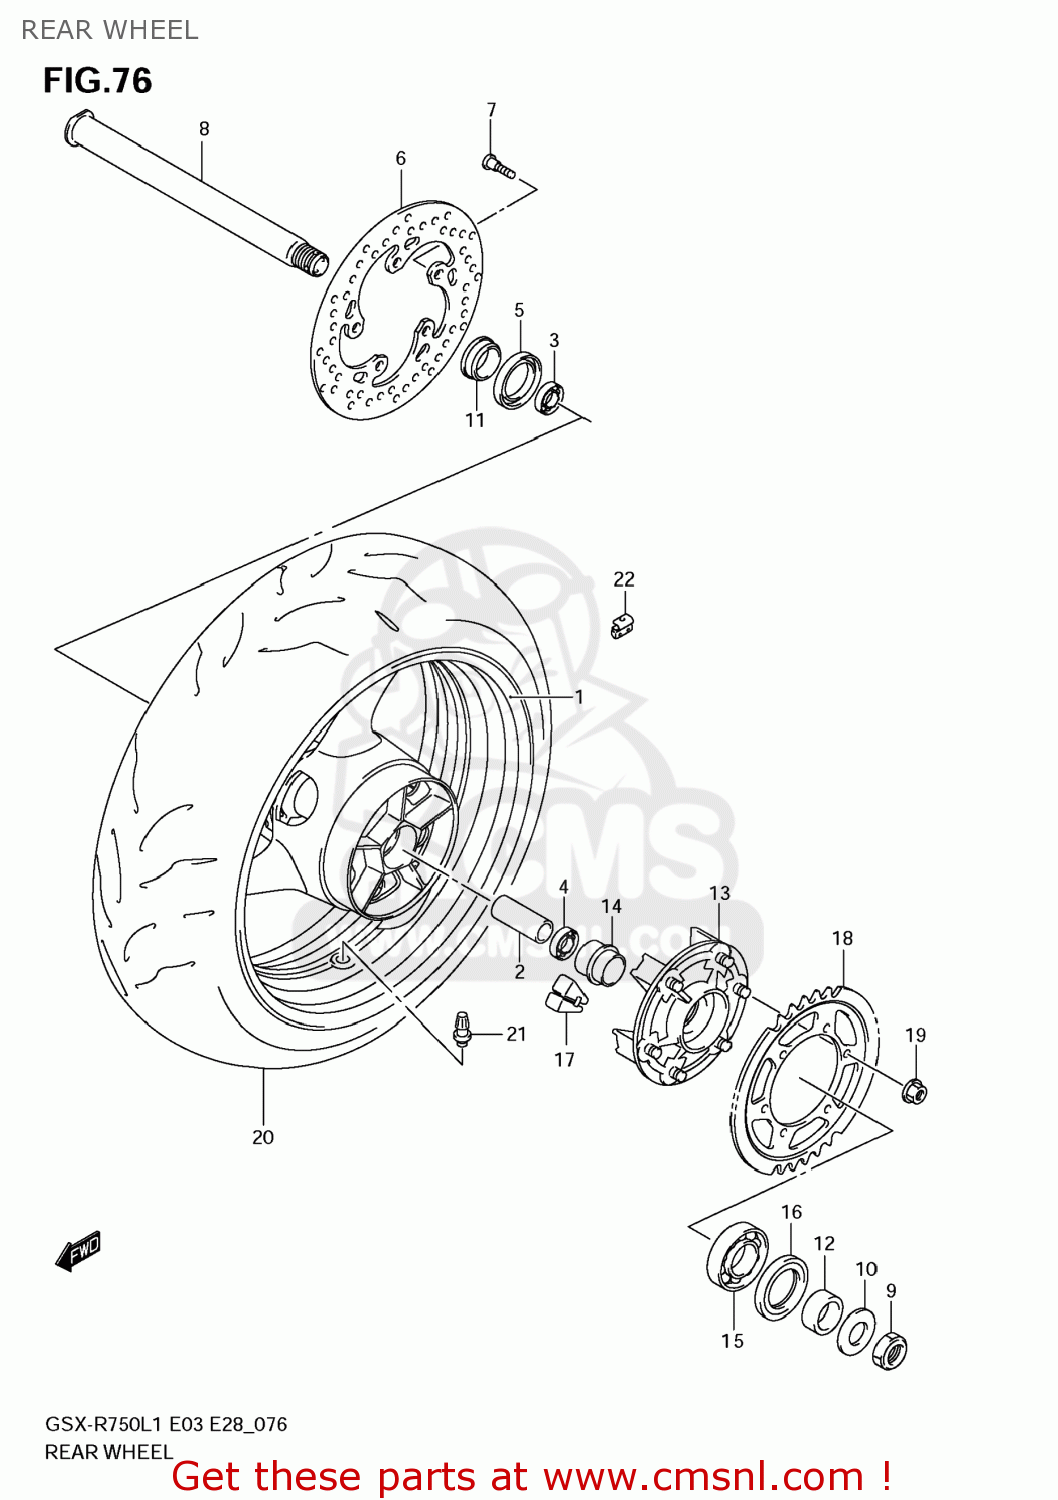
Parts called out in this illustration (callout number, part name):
1	WHEEL,RR(17M/CXMT5.50)
2	SPACER,RR WHEEL BEARING
3	BEARING(25X52X15)
4	BEARING
5	SEAL,OIL(32X52X7)
6	DISC,RR BRAKE
7	BOLT(8X21)
8	AXLE,RR
9	NUT
10	WASHER(22X35X2)
11	SPACER,FRONT A
12	SPACER,RR AXLE,L
13	DRUM,RR SPROCKET
14	RETAINER,RR SPROCKET DRUM
15	BEARING
16	SEAL,OIL(39X65X7)
17	ABSORBER,RR HUB SHOCK
18	SPROCKET,RR(45T-525)
19	NUT
20	TIRE,RR
21	VALVE ASSY,WHEEL RIM(TR412)
22	BALANCER,WHEEL(10G)
